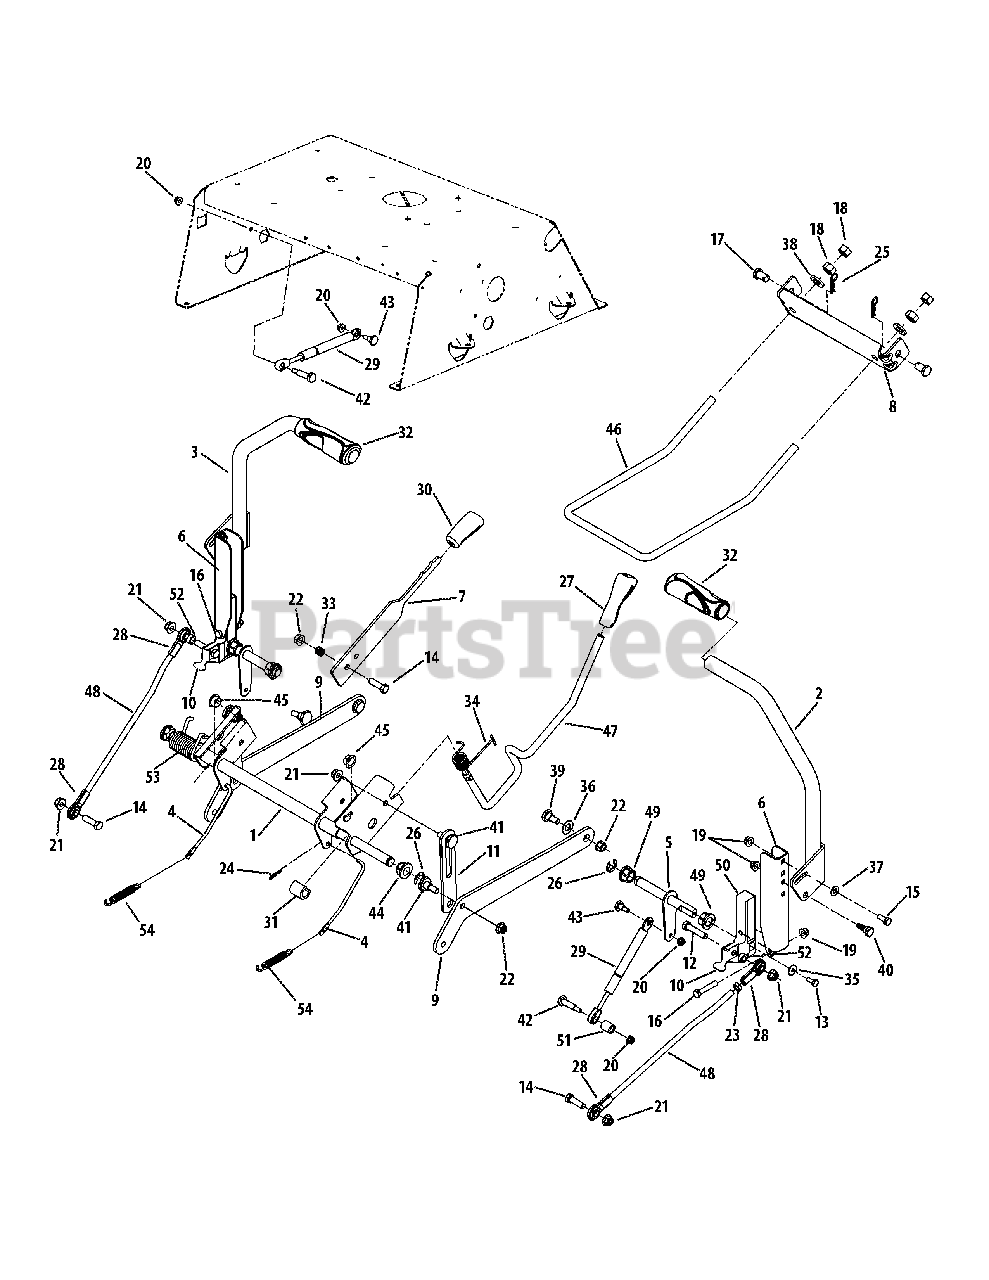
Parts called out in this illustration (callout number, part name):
1	Deck Lift Shaft Assembly
2	Lapbar Lever RH
3	Lapbar Lever LH
5	Control Shaft
6	Lapbar Pivot Bracket
8	Front Deck Hanger Bracket
9	Deck Lift Arm
10	Switch Actuator Bracket
11	Lift Link Plate
12	Hex Screw, 3/8-16 x 1.75
13	Hex Lock Screw, 1/4-20 x .62
14	Hex Cap Screw, 3/8-16 x 1.25
15	Hex Cap Screw, 5/16-18 x .75
16	Hex Cap Screw, 5/16-18 x 1.75
17	Clevis Pin, .50 x .78
18	Hex Nut, 1/2-13
19	Hex Flange Insert Lock Nut, 5/16-18
20	Hex Flange Insert Lock Nut, 1/4-20
21	Hex Flange Insert Lock Nut, 3/8-16
22	Hex Flange Lock Nut, 3/8-16
23	Jam Nut, 3/8-24
24	Bow-Tie Cotter Pin
25	Cotter Pin
26	E-Ring, .625 Dia.
27	Handle Grip
29	Damper Cylinder
30	Handle Grip
31	Spacer, .62 x 1.0
32	Hand Grip
33	Compression Spring
34	Spring, Torsion RZT
35	Bell Washer, .265 x .75 x .062
36	Flat Washer, .51 x 1.0 x .06
37	Flat Washer, .344 x .688 x .065
38	Flat Washer, .531 x 1.062 x .134
39	Shoulder Screw, .498 x .340 x 3/8-16
40	Shoulder Screw, .437 x .268 x 5/16-18
41	Shoulder Screw, .5 x .434 x 3/8-16
42	Shoulder Screw, .374 x 1.16 x 1/4-20
43	Shoulder Screw, .375 x .38 x 1/4-20
44	Hex Flange Bearing
45	Flange Bearing, .626 x .938 x .344
46	Deck Front Hanger Rod
47	Deck Lift Handle Rod
48	Lapbar Control Rod
49	Hex Flange Bearing
50	Control Hub
51	Spacer, .385 x .630 x .75
52	Spacer, .380 x .625 x .265
53	Torsion Spring
54	Extension Spring, .59 x 4.00
